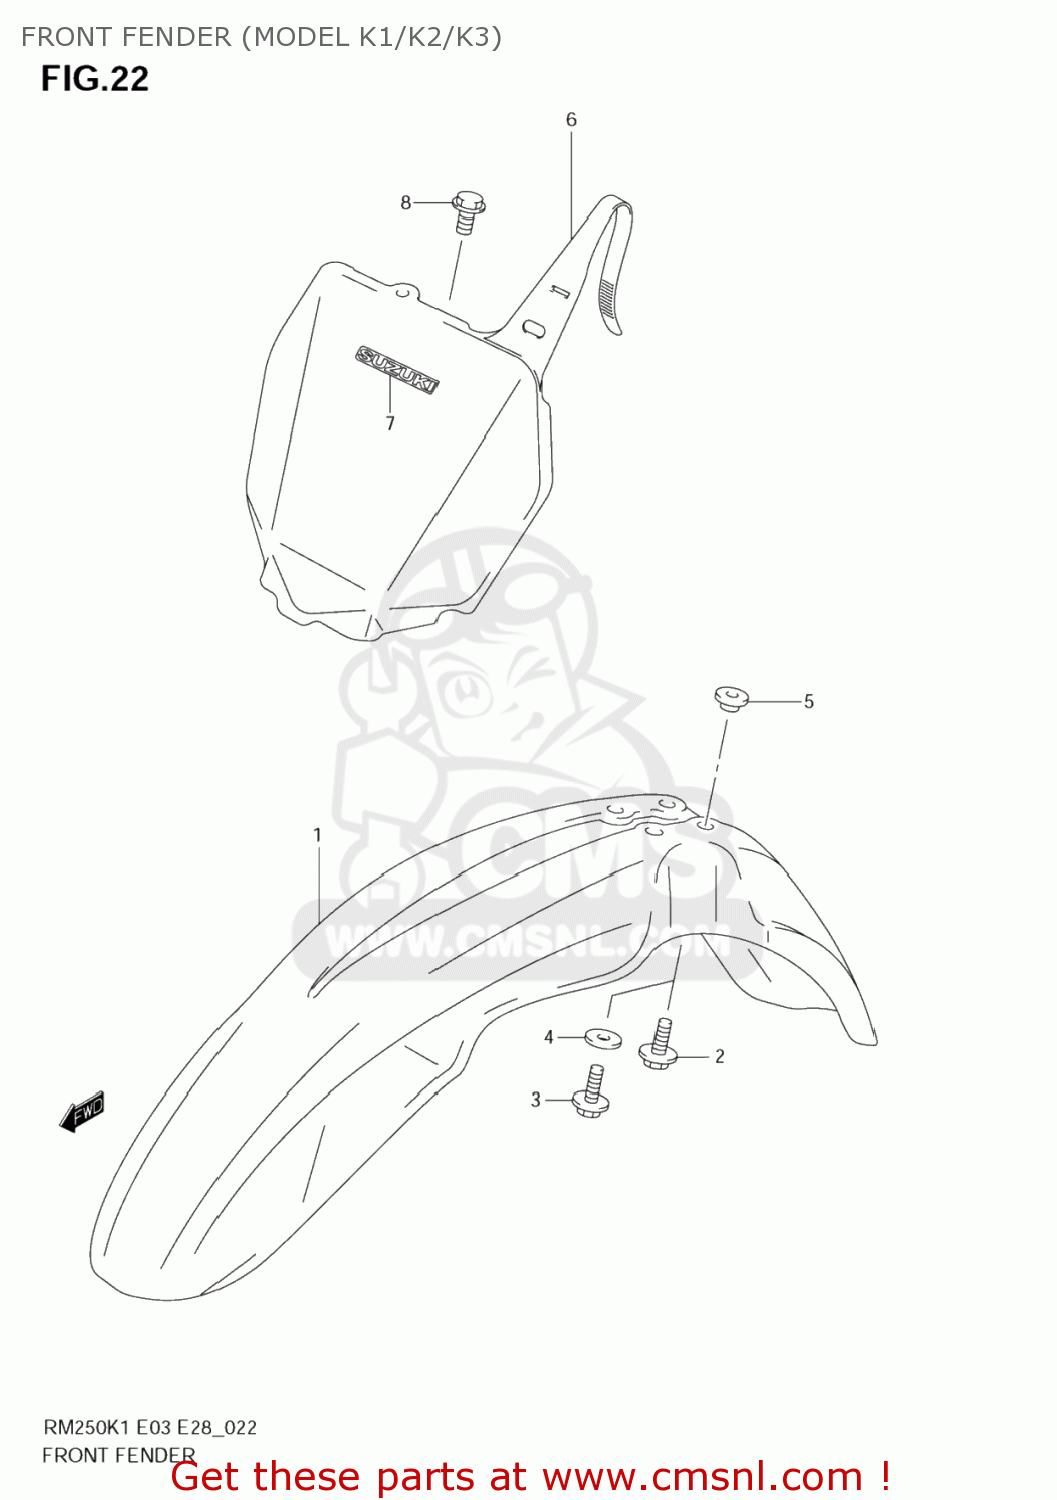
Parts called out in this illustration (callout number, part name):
1	FENDER,FR
2	BOLT(6X16)
3	BOLT
4	WASHER(6.5X28X1.6)
5	WASHER
6	PLATE,NUMBER F
7	EMBLEM,SUZUKI
8	BOLT
